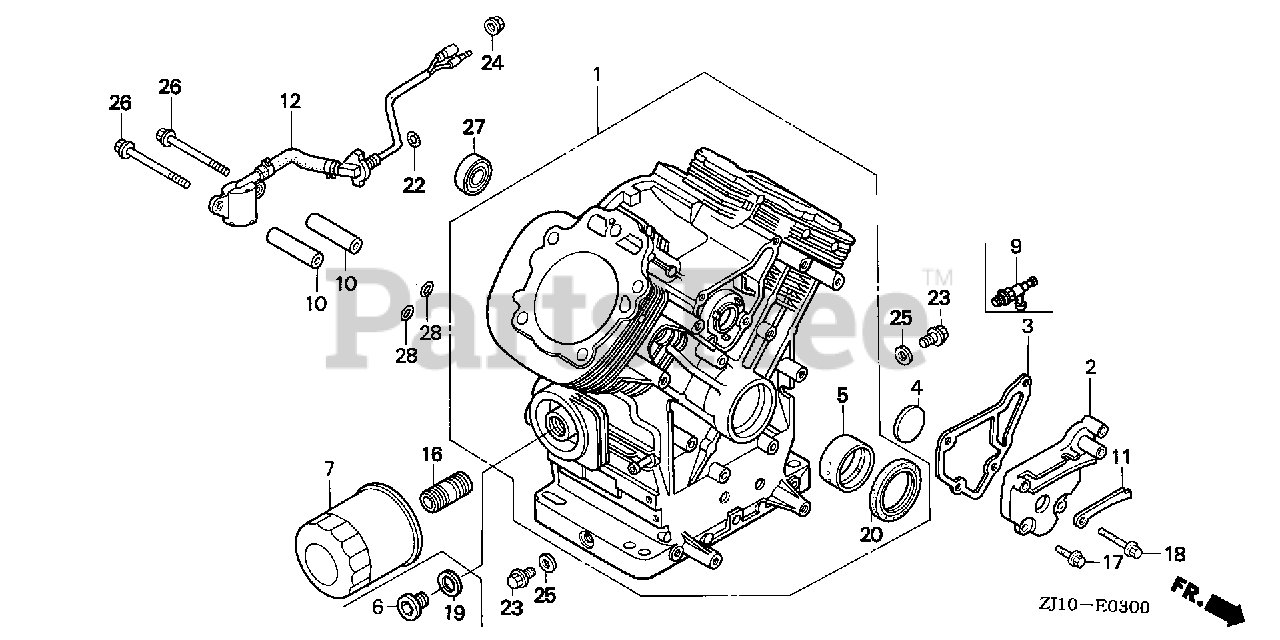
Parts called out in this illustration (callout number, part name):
1	CYLINDER ASSY. (W/O-PUMP)
2	COVER, BREATHER
3	GASKET, BREATHER COVER
4	VALVE, BREATHER
5	BEARING A, MAIN (BLUE) (TO SELECT CORRECT BEARING, SEE THE SERVICE MANUAL.)
5	BEARING B, MAIN (BLACK) (TO SELECT CORRECT BEARING, SEE THE SERVICE MANUAL.)
5	BEARING C, MAIN (BROWN) (TO SELECT CORRECT BEARING, SEE THE SERVICE MANUAL.)
7	FILTER, OIL (FILTECH TOYO ROKI) (SOLD INDIVIDUALLY)
7	FILTER, OIL (TOYO ROKI) (SOLD INDIVIDUALLY)
9	VALVE, DRAIN (14X1.5)
11	CLAMP, WIRE
16	HOLDER, OIL FILTER
17	BOLT, FLANGE (6X16) (CT200)
18	BOLT, FLANGE (6X32) (CT200)
20	OIL SEAL (38X58X11)
23	BOLT, DRAIN PLUG (14MM)
25	WASHER, DRAIN PLUG (14MM)
27	BEARING, RADIAL BALL (6003)
28	O-RING (13X3.0)
